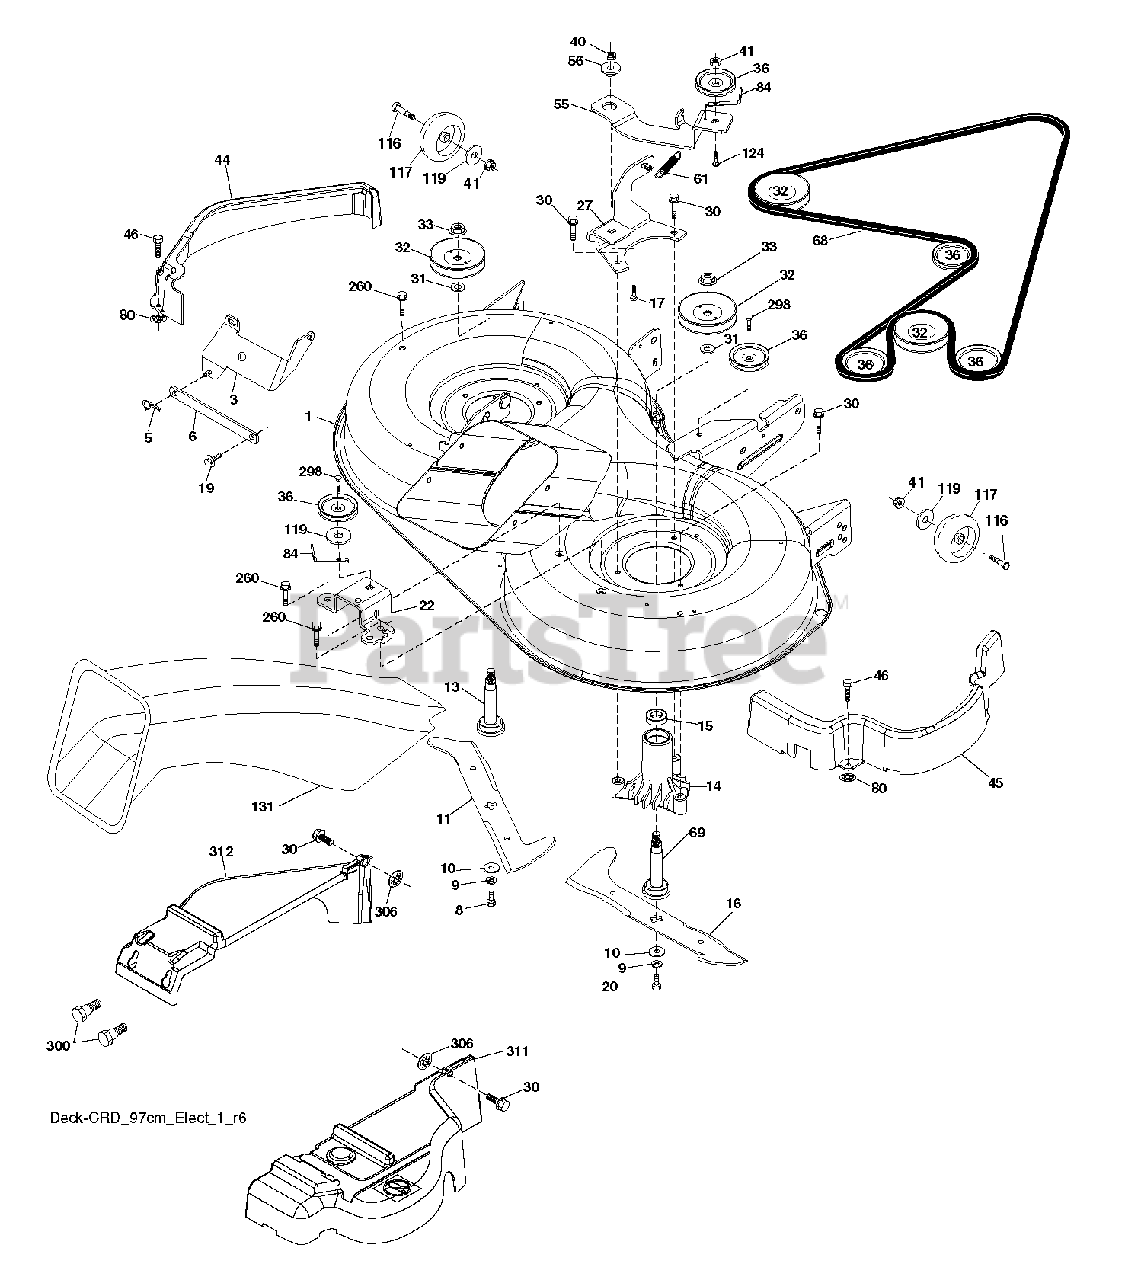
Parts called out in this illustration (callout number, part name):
1	DECK.WLDT.97.CRD.2GWB.
3	BRACKET.ASM.BAR.SWAY.CHASS
5	Retainer Spring
6	BAR.SWAY.92.CRD
8	BOLT.3/8-24X1.25 GR8
9	LOCKWASHER
10	WASHER.BLADE
11	BLADE.3N1.LH.CRD.97
13	SHAFT ASM VENT
14	HOUSING.MANDREL.VENTED (MACHD)
16	BLADE.3N1.RH.CRD.97
17	BOLT.3/8-14X1.25
19	BOLT SHD 5/16-18
20	BOLT.3/8-24X1.25GR8. LHTHRD
22	BRACKET.SUPT.IDLER.REAR.RH
27	BRACKET.ASM.SUSP.REAR.RH.
30	SCREW, WASHER HEAD
31	WASHER.SPACER.MANDREL
32	PULLEY MANDREL
33	NUT.FLANGE.LOCK.TOP
36	PULLEY.IDLER.4.25
41	NUT LOCK FLG 3/8-16 UNC
44	COVER MANDREL LEFT
45	COVER MANDREL RIGHT
46	SCREW.1/4-20X5/8
55	ARM.IDLER.92 CRD.2006
56	SPACER.RETAINER.MOWER
61	SPRING
68	BELT.DRIVE.CRD.97.2010
69	SHAFT.ASM.W/LWR.BRG.RH.THREAD
80	PALNUT 1/4
84	KEEPER, BELT IDLER
116	BOLT.SHOULDER.3/8-16X3-5/8.
117	WHEEL. GUAGE RALLY
119	WASHER
124	BOLT.3/8-16X1.50
131	CHUTE BAGGER
260	SCREW 3/8-16X1/2
298	SCREW LT
300	BOLT.SHOULDER
306	WASHER 5/16"
311	COVER RIGHT
312	COVER LEFT
